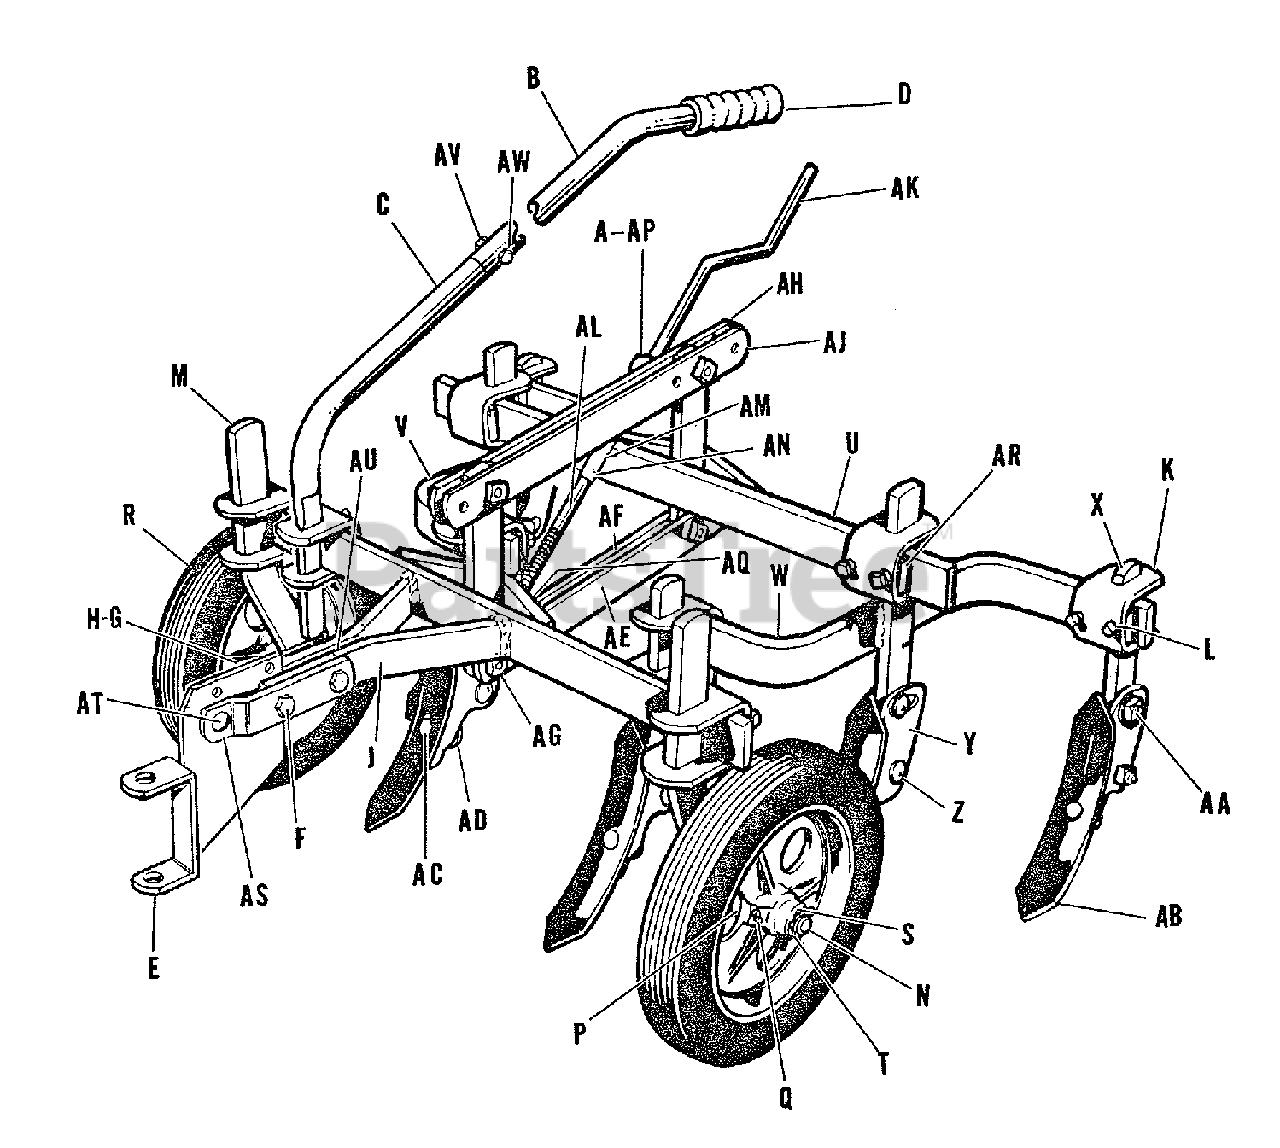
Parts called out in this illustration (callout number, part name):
A	PIN, Cotter, 1/8" Diameter x 1" LG
B	HANDLE, Control, Upper
C	HANDLE, Control, Lower
D	GRIP, Handle
E	END ASSEMBLY, Drawbar
F	BOLT, Carriage, 3/8"-16 NC x 1-3/4" LG
G	WASHER, Lock, 3/8"
H	NUT, Hex, Full, 3/8"-16 NC
J	DRAWBAR ASSEMBLY
K	CLAMP, Shank
L	SCREW, Set, Cup Point, Square Head, 3/8"-16 NC x 1" LG
M	STANDARD, Wheel
N	SPINDLE, Wheel
P	NUT, Ham, Hex, 5/8"-11 NC
Q	FITTING, Grease
R	WHEEL, Complete
T	PIN, Cotter, 1/8" Diameter x 1" LG
U	TOOL BAR ASSEMBLY
V	FRAME ASSEMBLY, Tool, R.H.
W	FRAME ASSEMBLY, Tool, L.H.
X	STANDARD, Tool, Short
Y	TOOL HOLDER ASSEMBLY
Z	BOLT, Carriage, 3/8"-16 NC x 1-1/4" LG
AA	WASHER, Plain, 3/8"
AB	STEEL, Cultivator
AC	BOLT, Plow, 3/8-16 x 2-1/4"
AD	WASHER, Plain, 3/8"
AE	BAR, Parrallel, R.H.
AF	BAR, Parrallel, L.H.
AG	SCREW, Cap, Hex, 3/8"-16 NC x 1-1/4" LG
AH	BAR, Parallel, R.H.
AJ	BAR, Parallel, L.H.
AK	SCREW, Upper
AL	SCREW, Lower
AM	COUPLING, Screw
AN	RIVET, Round Head
AP	NUT, Adjusting, Upper
AQ	NUT, Adjusting, Lower
AR	NUT, Special
AS	EXTENSION, Draw Bar
AT	BOLT, Carriage, 3/8"-16 NC x 1-1/4" LG
AV	NUT, Hex, Jam, 5/16-18 NC
AW	CAPSCREW, Hex, Head, 5/16-18 NC x 1-1/4" LG
